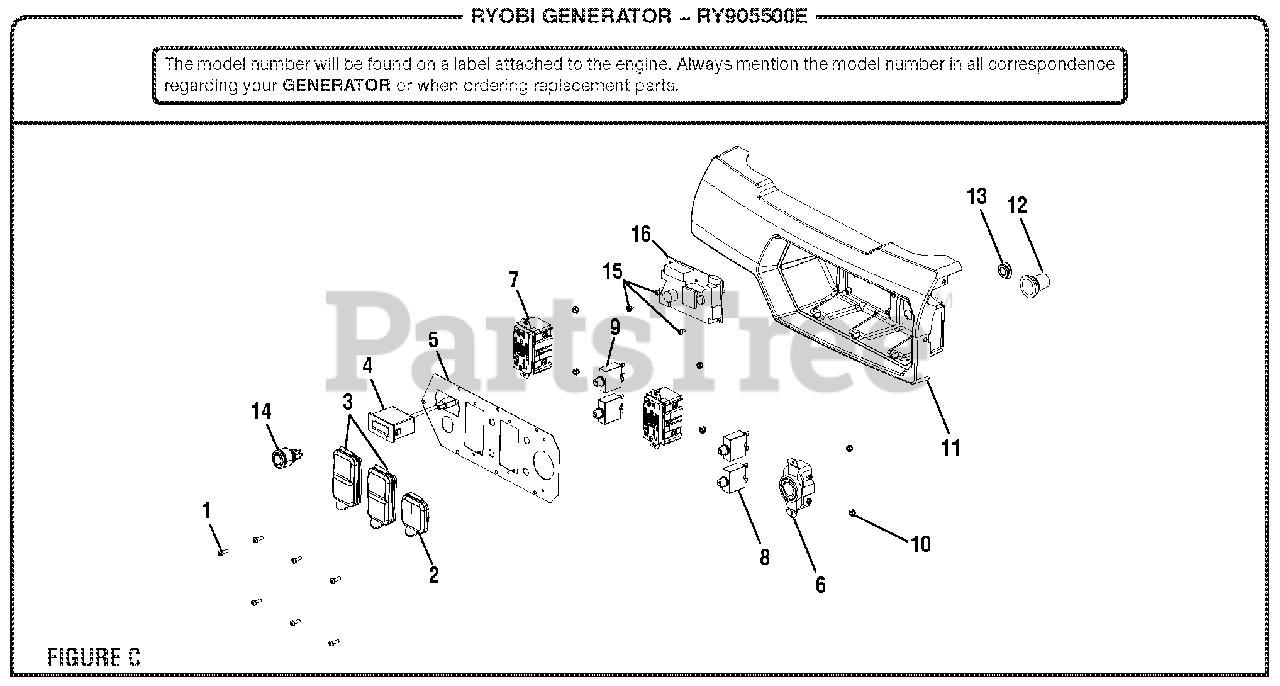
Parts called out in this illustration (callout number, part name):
1	Screw (M8-18 x 1/2 in. T20 Torx Hd.)
2	Outlet Cover
3	Duplex Outlet Cover
4	Digital Meter
5	Front Panel
6	Twist Lock Recepticle (120/240 Volt, 30 Amp, L14-30)
7	Duplex Receptacle (120V)
8	Circuit Breaker (25 Amp)
9	Circuit Breaker (20 Amp)
10	Lock Nut (#6-32)
11	Control Box (Back Panel)
12	Rubber Boot
14	Engine Start Push Switch
15	Screw (M3 x 5 mm)
16	Battery Charger
